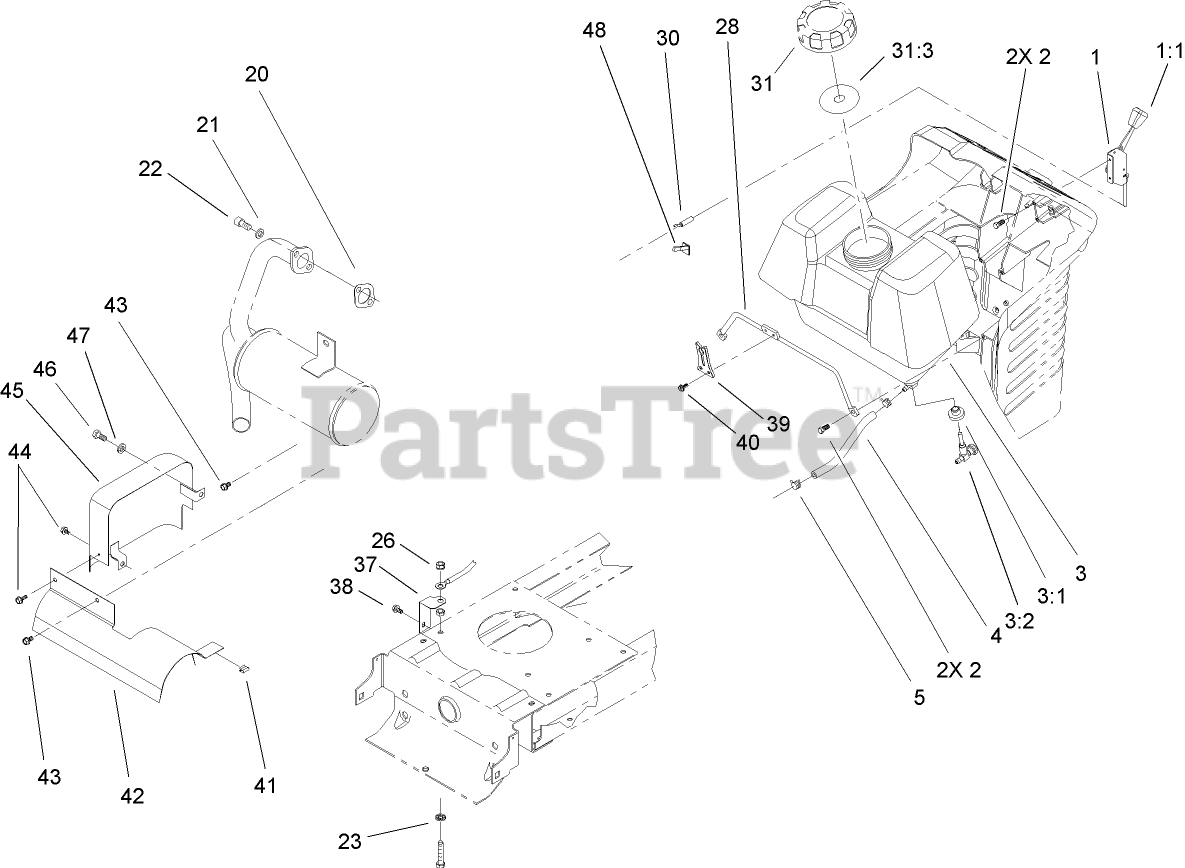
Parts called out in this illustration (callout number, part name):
1	THROTTLE CONTROL ASM
2	SCREW-SPECIAL
3	GAS TANK ASM
3:1	BUSHING
3:2	VALVE-FUEL
4	HOSE-FUEL
5	CLAMP-HOSE
20	GASKET-EXHAUST
21	WASHER-LOCK
22	SCREW-HSH
23	WASHER-LOCK
26	NUT-KEPS
28	ROD-TANK, GAS
30	THROTTLE CABLE ASM
31	GAS CAP ASM
31:3	GASKET-CAP, GAS
37	BRACKET-GROUND
38	SCREW-HWH
39	LATCH-HOOD
40	SCREW-HWH
41	CLIP-TINNERMAN
42	SHIELD-MUFFLER
43	SCREW-HWH
44	SCREW-HWHTF
45	HEAT SHIELD ASM
46	SCREW-HH
47	WASHER-LOCK
48	REDUCER-THROTTLE, RPM
